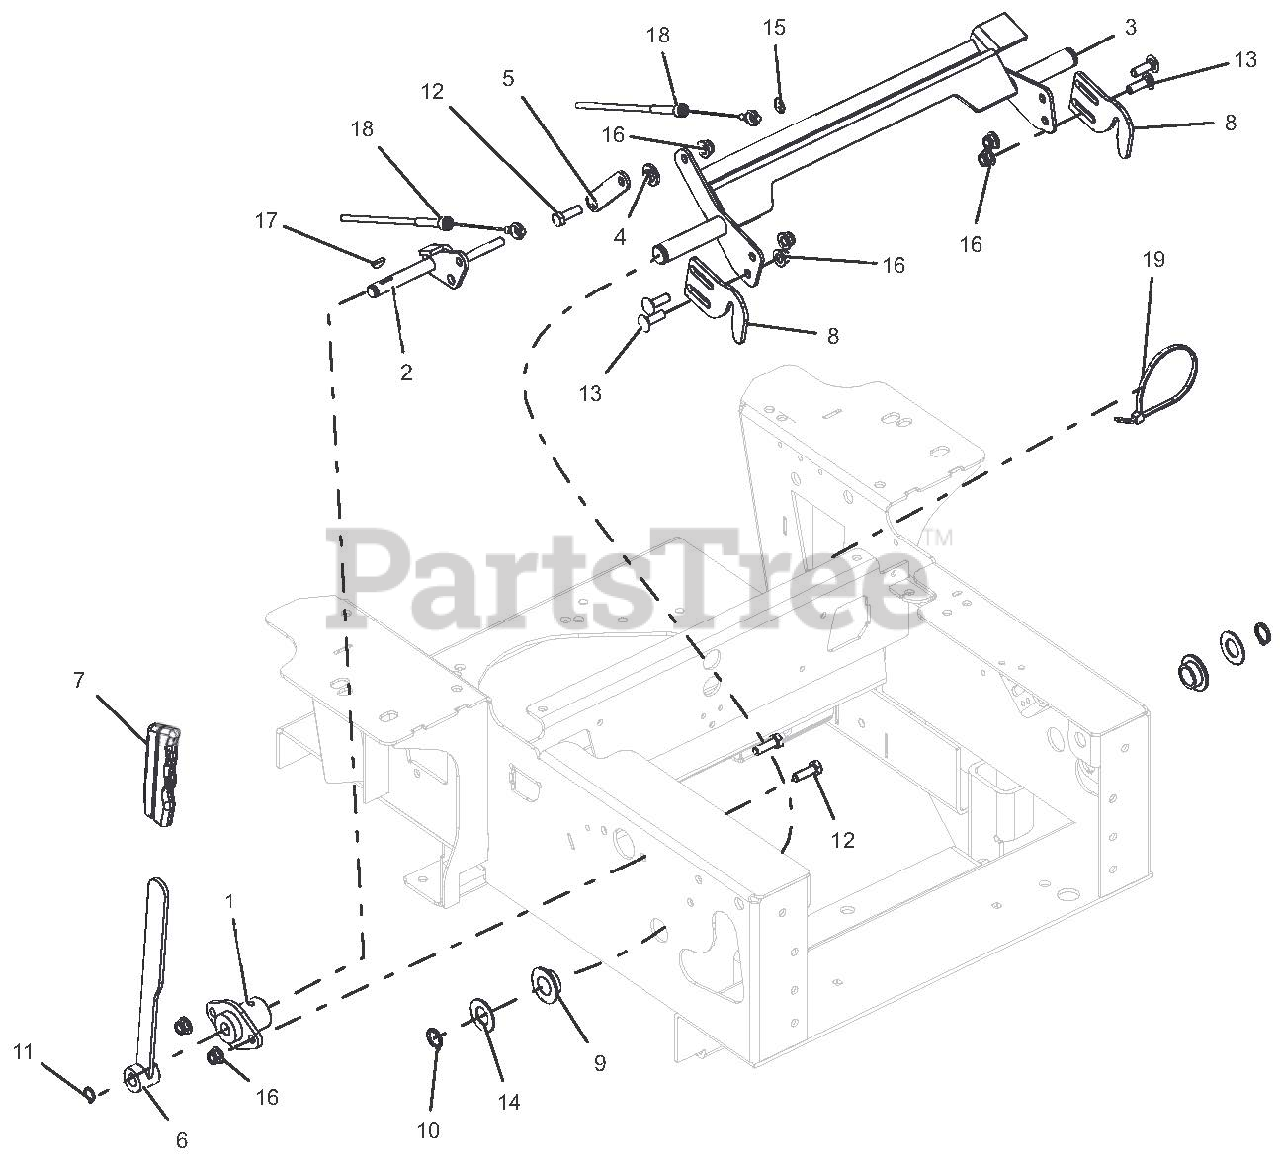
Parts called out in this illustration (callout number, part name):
1	BSHG, FLANGE .500 ID
2	WLDMT, PARK BRAKE ARM
3	WLDMT, PT100 NEUTRAL LOCK
4	BSHG, FLG .325X.499X.26X.88
5	PLATE, NEUTRAL INTERLOCK
6	WLDMT, PARKING BRAKE ARM
7	GRIP, PARKING BRAKE
8	NEUTRAL, LOCK LATCH-BLACK
9	BSHG, FLANGE .762 X 1.48 X .44 NYLON
10	RG-RTNG-EXT .750x.078
11	RG-RTNG-EXT .500x.050
12	BLT-HEX .31-18X1.00 GR5 YWZC
13	BLT-RDHDSQSHNK .31-18X1.00 G5 Y
14	WSHR-FL-STL .755X1.375X.062 YWZC
15	NUT, PUSH .312
16	NUT-LK-NYL-FLG .31-18 YWZC
17	KEY, WDRF .13x.63 HRD#5 GM124545 P
18	CABLE, BRAKE ACTUATING
19	CABLE, TIE 5.50 LG
